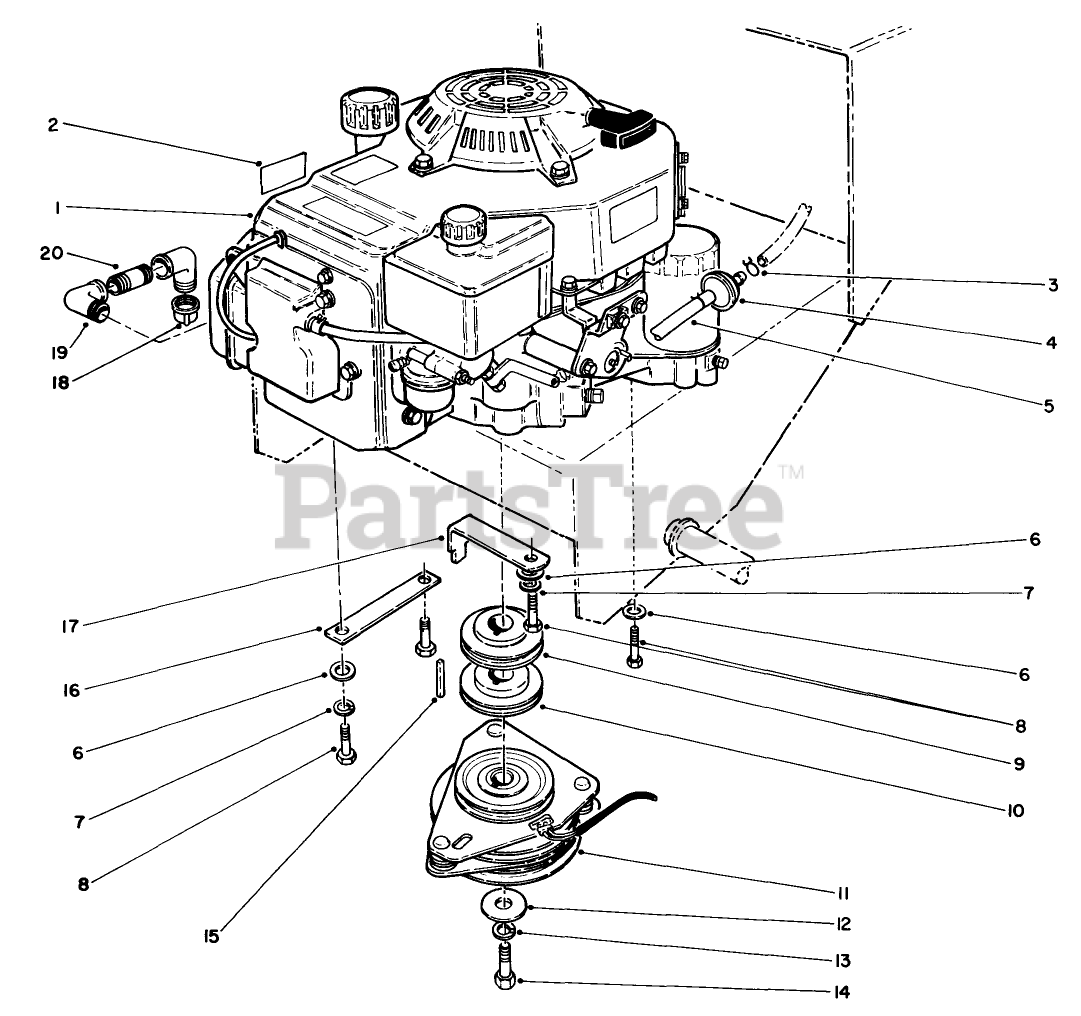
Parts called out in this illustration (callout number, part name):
1	Engine
2	DECAL-SURFACE, HOT
3	CLAMP-HOSE
4	FILTER-FUEL
6	WASHER-PLAIN
7	WASHER-LOCK
9	SHEAVE-HALF, UPPER
10	SHEAVE-HALF, LOWER
13	WASHER-LOCK
14	SCREW-CLUTCH
15	KEY-SQUARE
18	CAP-PIPE
19	ELBOW-STREET, 90 DEG
20	NIPPLE
